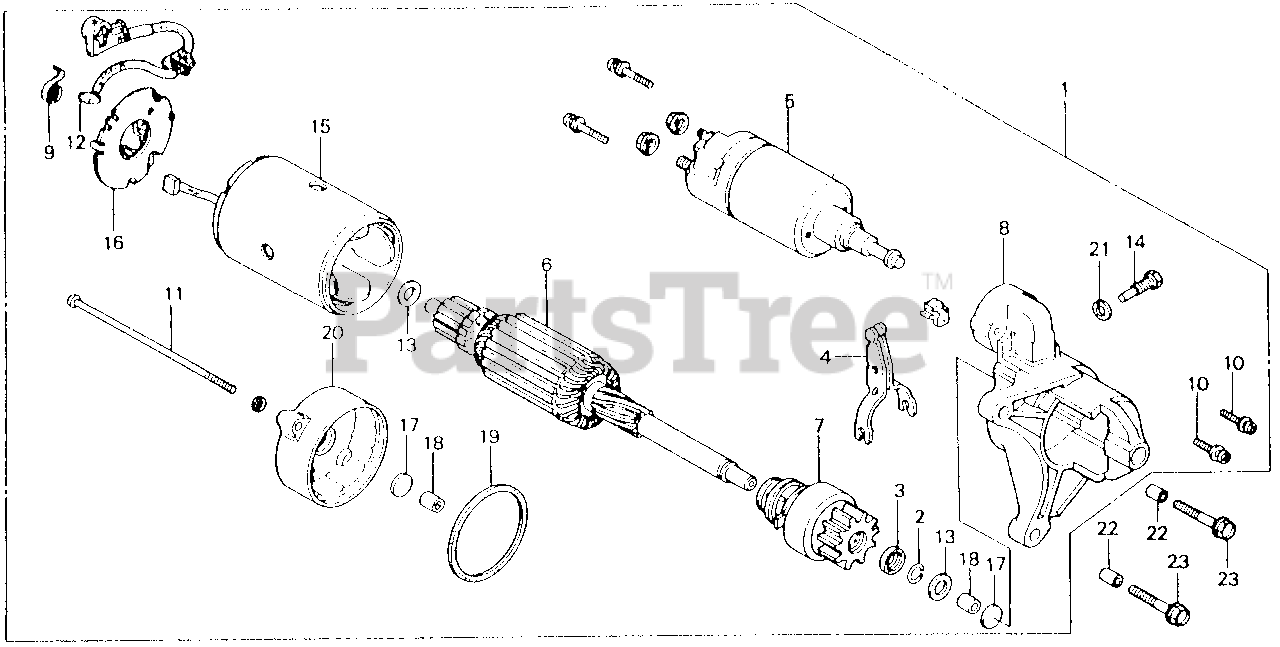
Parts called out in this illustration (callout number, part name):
1	MOTOR ASSY., STARTER
2	RING, SNAP (NOT AVAILABLE)
3	COLLAR, CLUTCH STOP
4	LEVER, PINION (NOT AVAILABLE)
5	SWITCH, MAGNETIC
6	ARMATURE (NOT AVAILABLE)
7	PINION
8	CASE, GEAR
9	SPRING, BRUSH
10	SCREW, MAGNETIC SWITCH SETTING
11	BOLT, THROUGH
12	BRUSH
13	WASHER
14	SCREW, ARMATURE SETTING
15	COIL, FIELD
16	HOLDER, BRUSH
17	COVER, BEARING
18	BUSH, BEARING
19	GASKET, RUBBER PLATE
20	COVER, RR.
21	WASHER, SPRING (8MM)
22	PIN A, DOWEL (10X16)
23	BOLT, FLANGE (8X35)
